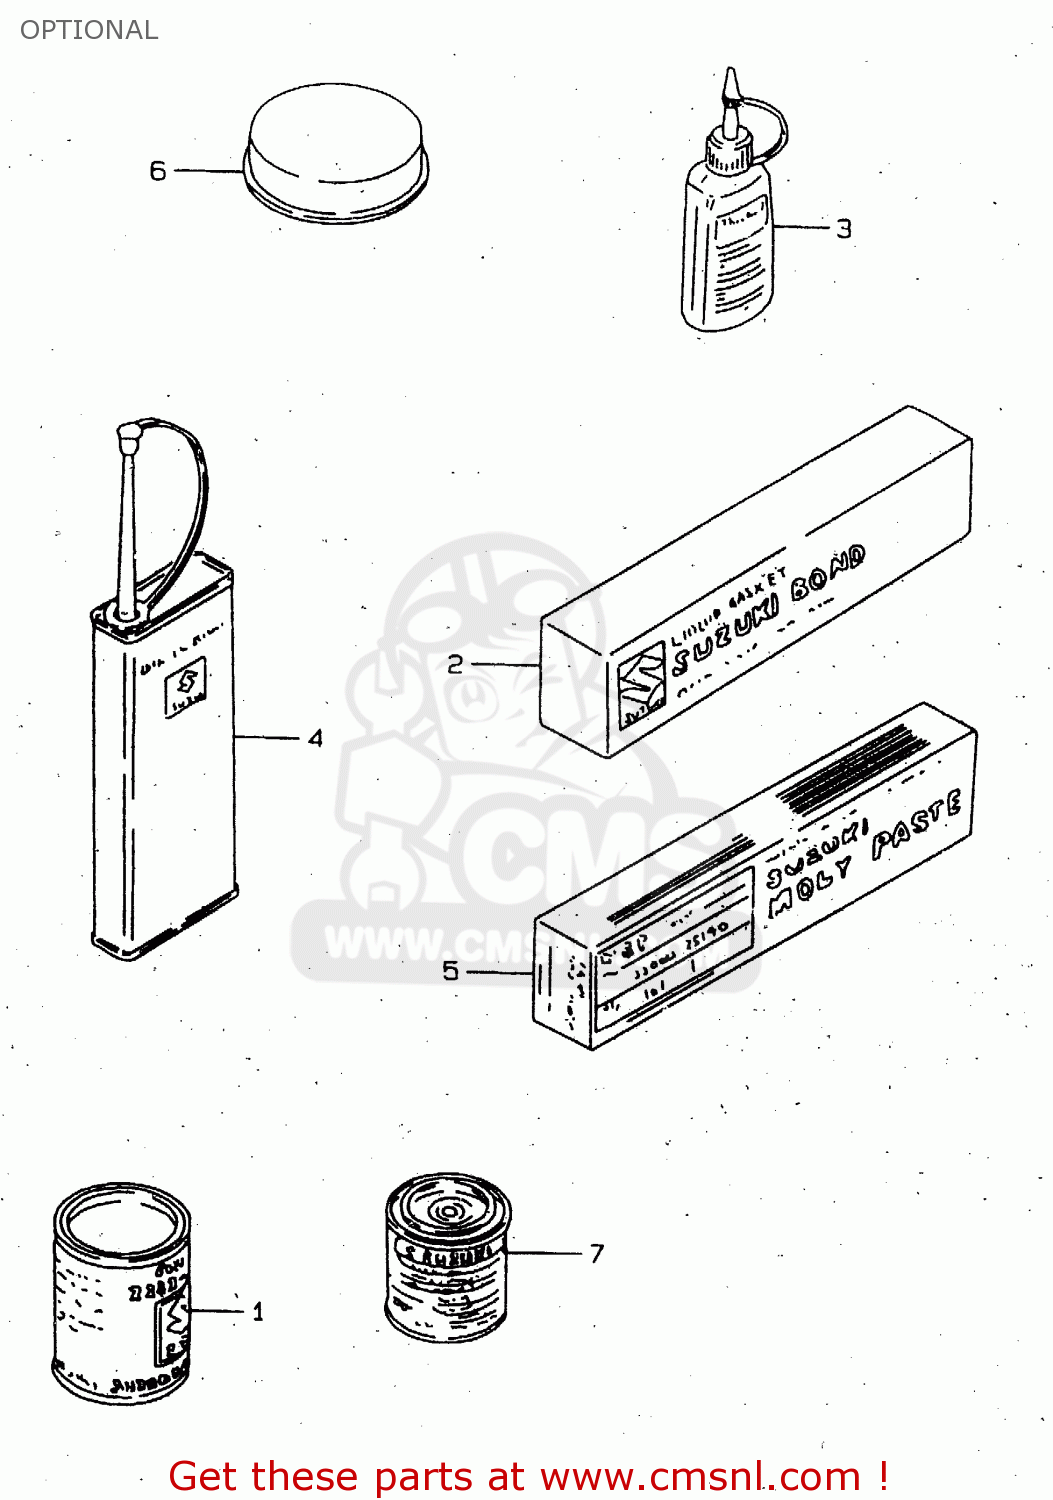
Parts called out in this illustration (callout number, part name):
1	GREASE(C)EP2 LITHIUM 150G
2	LIQUID GSKT NO.1215 250G
3	THREAD LOCK NO.1342
4	THREAD LOCK NO.1401 CLEAR 200G
5	SUZUKI MOLY PASTE
6	GREASE,PBC FOR BRK PAD 20G
7	PAINT,BLACK
